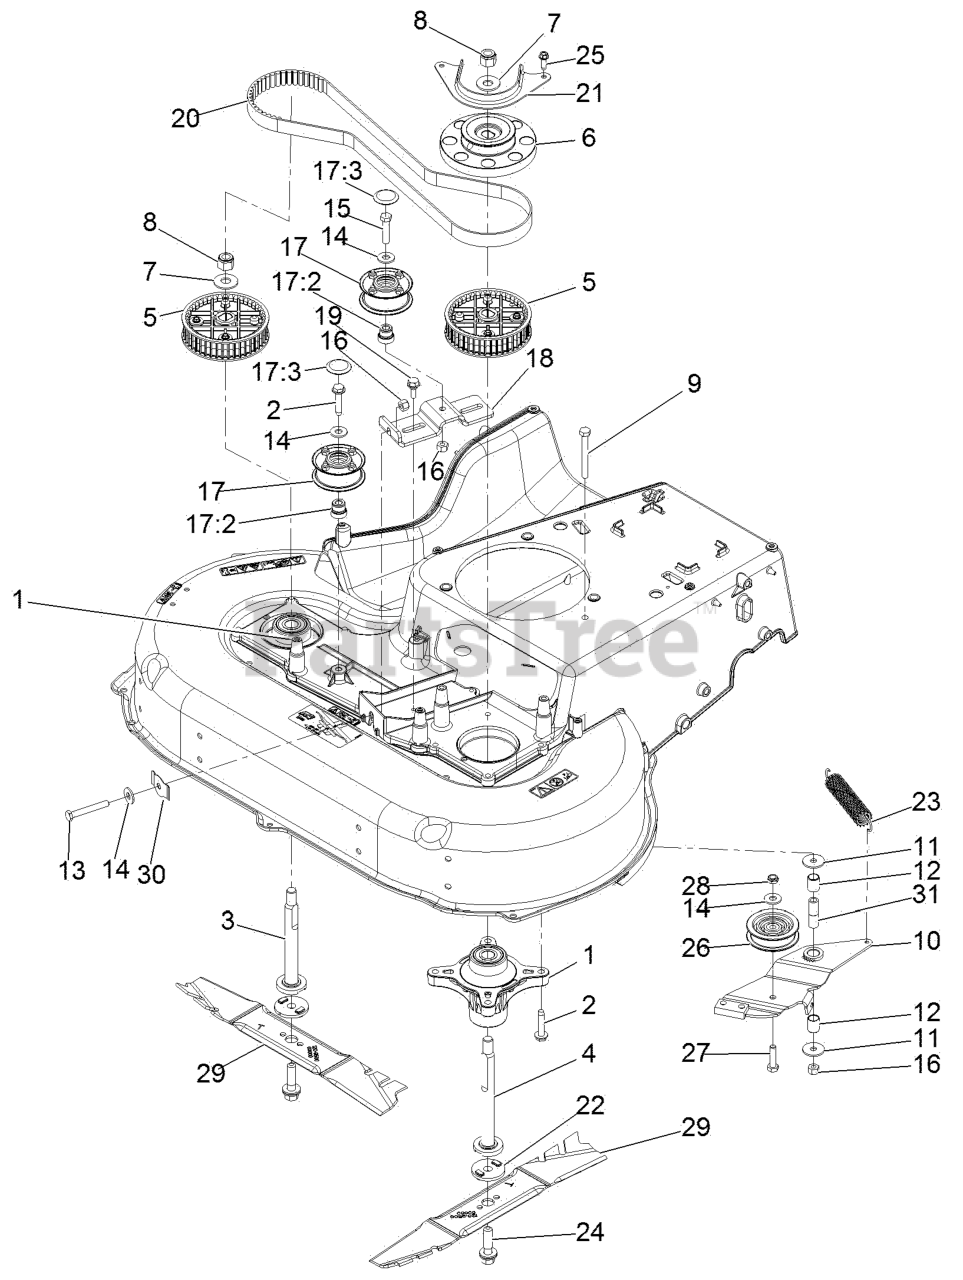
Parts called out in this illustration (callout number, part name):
3	SHAFT-SPINDLE
4	SHAFT-SPINDLE
5	SPROCKET
6	PULLEY-BRAKE, SPINDLE
7	WASHER-SPRING
8	NUT-HEX
9	SCREW-HH
11	WASHER-PIVOT
12	BUSHING-SLEEVE
13	BOLT-TAP, HH
14	WASHER-FLAT
15	SCREW-HH
16	NUT-LOCK, NI
17	PULLEY KIT
17:2	ADAPTER-BORE
17:3	PLUG-CAP
18	BRACKET-IDLER
19	SCREW-SHOULDER,HWH
20	BELT-SYNCHRONOUS
21	GUIDE-BELT, SPINDLE
22	ADAPTER-BLADE
23	SPRING-EXTENSION, BRAKE
24	BOLT-BLADE
25	SCREW-HWHTF
26	PULLEY-IDLER
27	SCREW-HH
28	NUT-LOCK, NI
29	BLADE-ROTARY
30	SPRING-FLAT
31	SPACER-BRAKE
